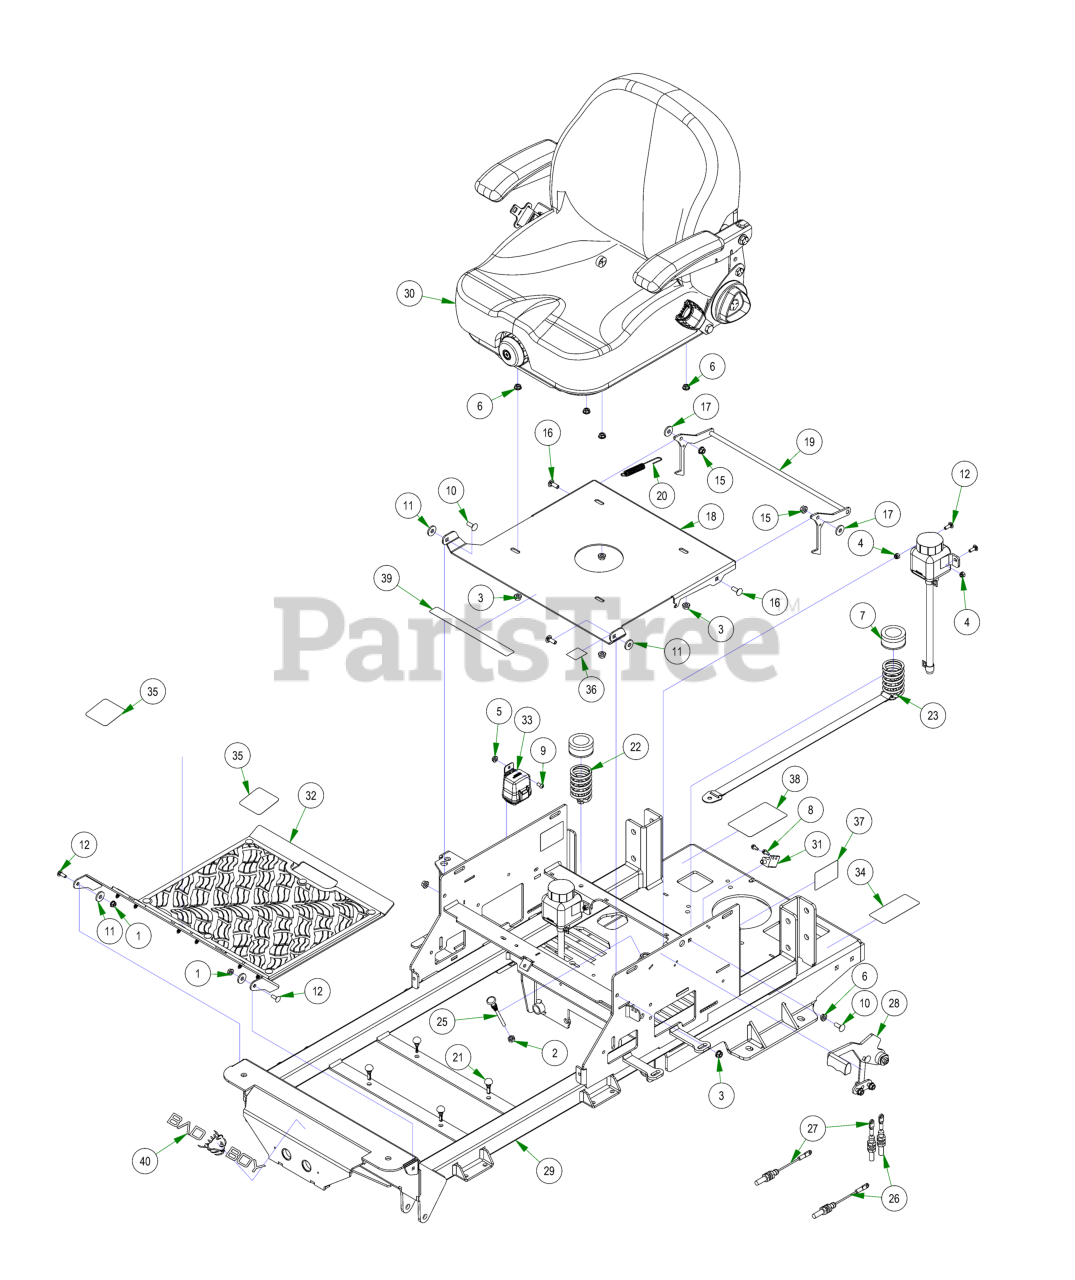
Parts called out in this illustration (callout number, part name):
1	1/4-20 NYL INSERT FLANGE LOCKNUT ZINC
2	3/8-24 HEX NUT ZINC YELLOW
3	5/16-18 NYLON INSERT FLANGE LOCKNUT ZINC
4	1/4-20 NYLON INSERT LOCKNUT ZINC
5	1/4-20 HEX SERRATED FLANGE NUT HARD/ZINC
6	5/16-18 HEX SERRATED FLANGE NUT HARD/ZINC
7	Seat Spring Cap Cover
8	12-24 X 1/2 HEX WASHER UNLSOT F TCS ZINC
9	1/4-20 X 1/2 BUTTON SOCKET CAP SCREW 18-8 STAINLESS STEEL
10	5/16-18 X 7/8 CARRIAGE BOLT ZINC
11	.360 ID X .983 OD X .120 THICK FLAT WASHER NYLON
12	1/4-20 X 3/4 CARRIAGE BOLT (GR.5) ZINC
13	2022 Maverick Rear Cover Assembly
14	MAVERICK/COMPACT OUTLAW SEAT PLATE ASSEMBLY
15	5/16-18 NYLON INSERT FLANGE LOCKNUT ZINC
16	5/16-18 X 7/8 CARRIAGE BOLT ZINC
17	.360 ID X .983 OD X .120 THICK FLAT WASHER NYLON
18	Seat Plate 2016
19	Seat Latch Rod Assembly
20	Brake Spring
21	2023 Floor Board Rubber Bumper
22	Seat Spring Assembly
23	2022 Mav/HD seat spring assembly with strap
24	ZT/Maverick Hydro Tank Hose
26	2021 Load Balanced Brake Cable 1
27	2021 Load Balanced Brake Cable 2
28	2021 Load Balanced Brake Handle Assembly
29	2023 Maverick Frame - Painted
30	2022 Suspension Seat w/Seatbelt
31	Safety Switch
32	2021 Maverick Floorboard Assembly
33	2024 Wiring Harness with Clips
34	2024 EPA Build Date Punch Decal
35	2018 Maverick/2021 ZT Anti-Skid Steering Control Decals
36	2018 MZ/Magnum/ZT/MAV/Comp Out Brake Decal
37	Hydraulic Decal
38	Maverick Pump Belt Decal
39	Outlaw Warning Decal
40	Flying Bulldog Front Bumper Decal
